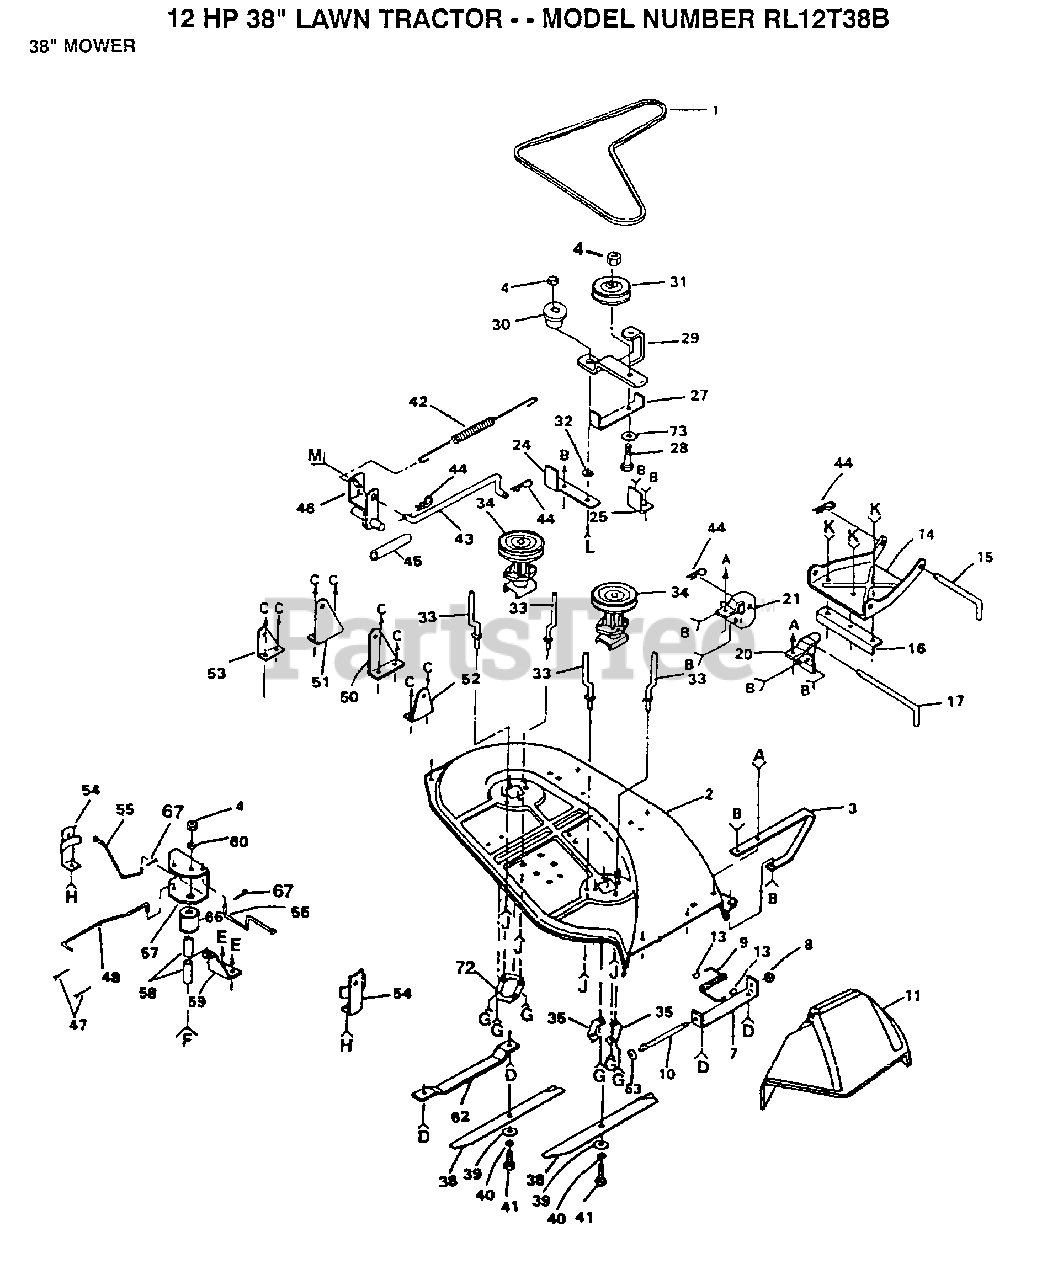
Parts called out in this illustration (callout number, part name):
1	BELT-V.79.1.MWR
5	WASHER M
6	BOLT
8	NUT PUSH M
10	ROD-HINGE T
11	DEFLECTOR-SHLD T
13	CAP-SLEEVE LT
14	LINK.PARALLEL
15	"ROD, FRT. PARAL T"
16	LINK STOP
17	HINGE PIN T
20	BRACKET RH LT
21	BRACKET LH T
22	BOLT
24	SUPPORT ARM T
25	STOP T
30	SPACER RETAINER
32	"WASHER, WEAR LT"
33	BELT KEEPER LT
35	SUPPORT PLATE LT
36	SCREW
37	SCREW
38	"BLADE.38"" HI-LI"
39	WASHER
41	BOLT.3/8-24X1-1/2
44	SPRING.RETAINER
45	SPACER T
48	ROD BRAKE LT
49	BOLT
52	"BRKT,SUSP RH T"
53	"BRKT,SUSP REAR LH"
54	BRAKE LT
55	"ROD, BRAKE LH LT"
56	ROD BRAKE LT
57	"BRK,BRAKE,PVT LT"
58	SPACER BRAKE LTV
59	BRACKET SUPT LTV
60	WASHER
61	BOLT
62	RUNNER-LH M
63	WASHER
64	BOLT.3/8-14X1.25
69	BOLT LT
70	WASHER T
72	SUPPORT T
73	WASHER
